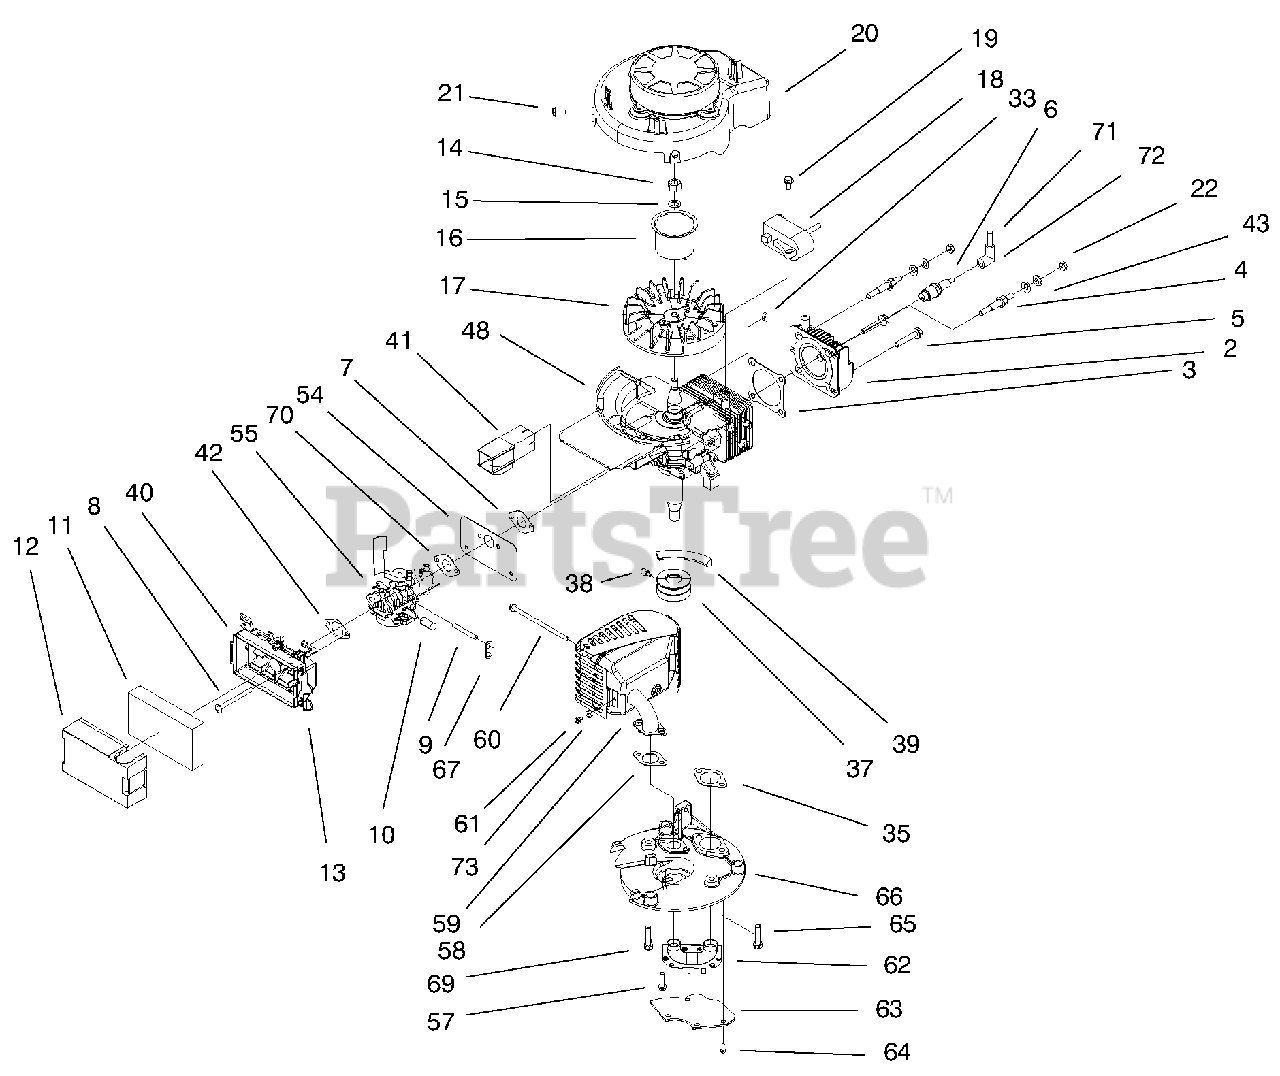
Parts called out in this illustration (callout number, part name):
3	Gasket-Head
6	Spark Plug
7	Intake Gasket
9	Primer Hose
11	Element-Air Filter
12	Cover-Air Filter
13	Retainer-Filter
15	Washer-Lock
16	Cup-Starter
17	Flywheel Machined Recoil
18	Ignition ASM
19	Screw-HWH
20	Shroud & Recoil ASM
21	Screw
22	Nut-Lock
35	Gasket-Exhaust
37	Pulley Engine
38	Screw-Set
40	Air Filter Base ASM
42	Gasket-Filter Base
42	Wire Lead
43	Washer-Lock
48	Short Block ASM Service
54	Heat Shield
55	Carburetor ASM
57	Screw-HWH
59	Muffler & Guard
62	Transfer Tube
63	Cover Plate
65	Screw-HH
66	Muffler Plate Machining
67	Retainer Hose
68	Sealer-Loctite
69	Screw-Hhd Washer
70	Retainer Wire
71	High Tension Lead & Cover
72	Cover & Terminal
73	Lockwasher
